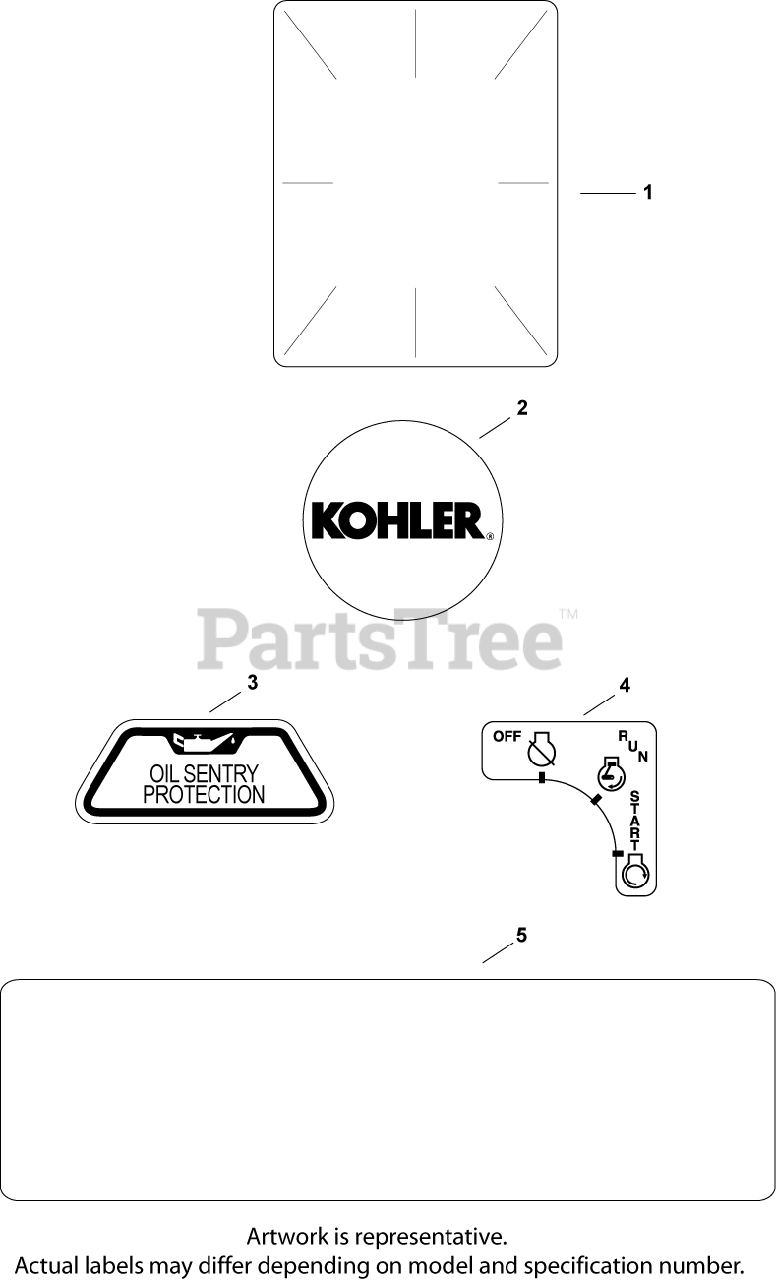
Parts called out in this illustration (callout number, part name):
1	DECAL, CLEAR LAMINATE USE 25 113 70-S
2	DECAL, GRASS SCREEN
3	DECAL, OIL SENTRY - (#DSC)
4	DECAL, KEY SWITCH
5	DECAL, COMMAND 27 HP
